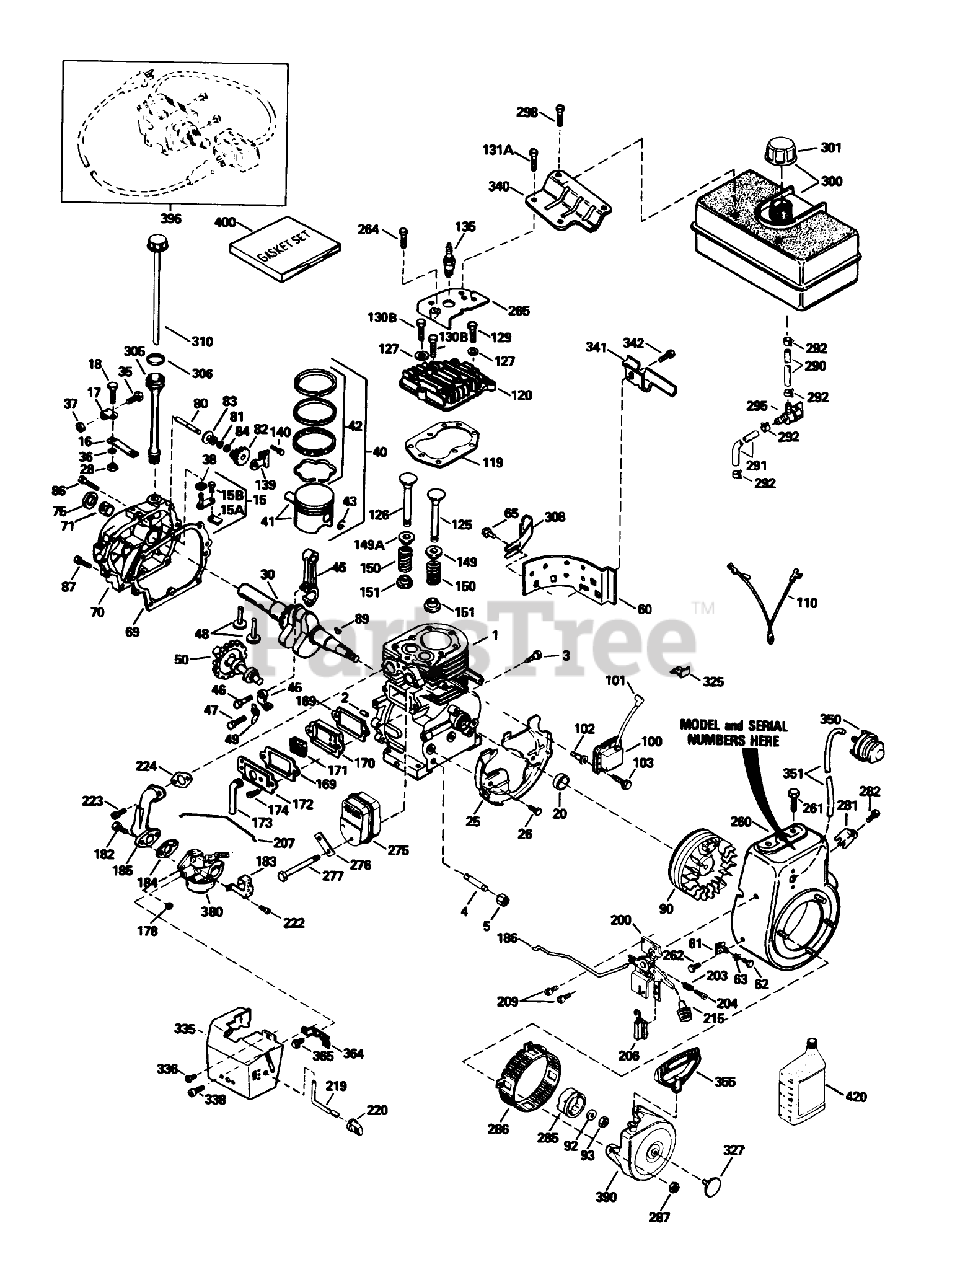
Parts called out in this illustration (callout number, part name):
1	Cylinder Asm (Includes 2, 20, 72)
2	Pin-Dowel
3	Screw (1/4-20x1/2)
4	Nipple-Pipe
5	Cap-Pipe
15	Rod, Governor (Incl. Nos.62 63)
15A	Yoke-Governor
15B	Screw (6-40x5/16)
16	Lever-Governor
17	Clamp-Lever, Governor
18	Screw
20	Seal-Oil
25	Baffle-Blower Housing
26	Screw (1/4-20x19/32)
28	Nut-Lock
30	Crankshaft
35	Screw
36	Washer-Lock
37	Nut-Lock
38	Ring-Retaining
40	Piston, Pin Ring Assy. (.010 oversize) (Incl. Ref. #24A, 25 26)
40	Piston, Pin Ring Assy.(Std.) (Incl. Ref. #24A, 25 26)
40	Piston, Pin Ring Assy. (.020 oversize) (Incl. Ref. #24A, 25 26)
41	Piston Pin Assy. (.020 oversize) (Incl. Ref. #26)
41	Piston Pin Assy. (.010 oversize) (Incl. Ref. #26)
41	Piston Pin Assy. (Std.) (Incl. Ref. #26)
42	Ring Set (Std.)
42	Ring Set (.020" OS)
42	Ring Set (.010" OS)
45	Rod Assy., Connecting (Incl. Ref. #28 28A)
46	Bolt-Rod
47	Bolt-Rod
48	Lifter-Valve
49	Dipper-Oil
50	Camshaft (MCR)
60	Extension-Housing, Blower
61	Bracket
62	Screw (8-32 x 3/8)
63	Grommet
65	Screw
70	Cover-Cylinder (Includes 71, 75, 80)
71	2025A77 WIZARD ROTA
75	Seal-Oil
80	Shaft-Governor
81	Washer-Flat
82	Gear Assy., Governor (Incl. Ref. #45)
83	Spool-Governor
84	Ring-Retaining
86	Screw (1/4-20x1-3/16)
87	Screw (1/4-20x1-11/16)
89	Key-Flywheel
90	Flywheel (W/Ring Gear)
92	Washer-Belleville
93	Nut-Flywheel
100	Solid State ASM
101	Cover-Spark Plug
103	Screw
110	Ground Wire
119	Gasket-Head, Cylinder
120	Head-Cylinder
125	Valve, Exhaust (Standard)(Incl. No. 9)
125	Valve, Exhaust (1/32" oversize)(Incl. No. 9)
126	Valve, Intake (Std.) (Incl. Ref. #58)
126	Valve, Intake (1/32" oversize) (Incl. Ref. #58)
127	Washer-Flat
129	Screw (5/16-18x1-25/32)
130B	Screw (5/16-18x1-1/2)
131A	Screw
135	Spark Plug-Resistor (R J19 L M)
139	Bracket-Gear, Governor
140	Screw (10-24x1/2)
149	Cap-Spring, Valve
149A	51106 GILSON ROTARY
150	Spring-Valve
151	Keeper-Spring, Valve
169	Gasket-Cover, Valve
170	Body-Breather
171	Element-Breather
172	Cover-Valve
173	Tube-Breather
174	Screw
178	Nut and Lock Washer (1/4-28)
182	Screw (1/4-28x1)
183	Bracket-Choke
184	Gasket-Carburetor To Intake Pipe
185	Pipe-Intake
186	Link-Governor
200	Bracket-Control (Includes 19, 203, 204, 206)
203	Spring-Compression
204	Screw
206	Terminal
207	Link-Throttle
209	Screw (10-32 x 1/2)
215	Knob-Control
219	Rod-Choke
220	Knob-Control
222	Screw (10-32 x 1/2)
223	Screw (T-30, 5/16-18x1-3/32)
224	Gasket-Pipe, Intake
260	Housing-Blower
261	Screw (5/16-18x3/4)
262	Screw
264	Screw (1/2-20x5/8)
265	Cover-Cylinder Head
275	Muffler
276	62513 SNWTHWR W/284
277	Screw
281	Screw
282	Screw (8-32 x 3/8)
285	Hub-Starter
286	Screen-Starter
287	Nut and Lock Washer (1/4-28)
290	Line-Fuel (8.62)
291	Line-Fuel
292	Clamp-Line, Fuel
295	Valve-Shut Off, Fuel
298	Screw (1/4-15x7/8)
300	Tank-Fuel (Includes 292, 301)
301	Cap-Fuel
305	Tube-Fill, Oil
306	O-Ring
308	Clip-Tube, Fill
310	Gauge Oil ASM
325	Clip-Wire
327	Plug Starter
335	Cover-Carburetor
336	Screw (10-32x1/2)
338	Screw (10-32 x 3/8)
340	Bracket-Tank, Fuel
341	Bracket-Tank, Fuel (Black)
342	Screw (1/4-20x19/32)
350	Primer-Asm
351	Line-Primer
355	Handle-Starter, Mitten Grip
364	Bracket-Carburetor
365	Screw (8-32x27/64)
380	Carburetor (Incl. Ref. #184)
390	Rewind Starter
396	Starter-Electric (110 Volt)
400	Gasket Set
420	Oil-Engine (SAE 5W30)
